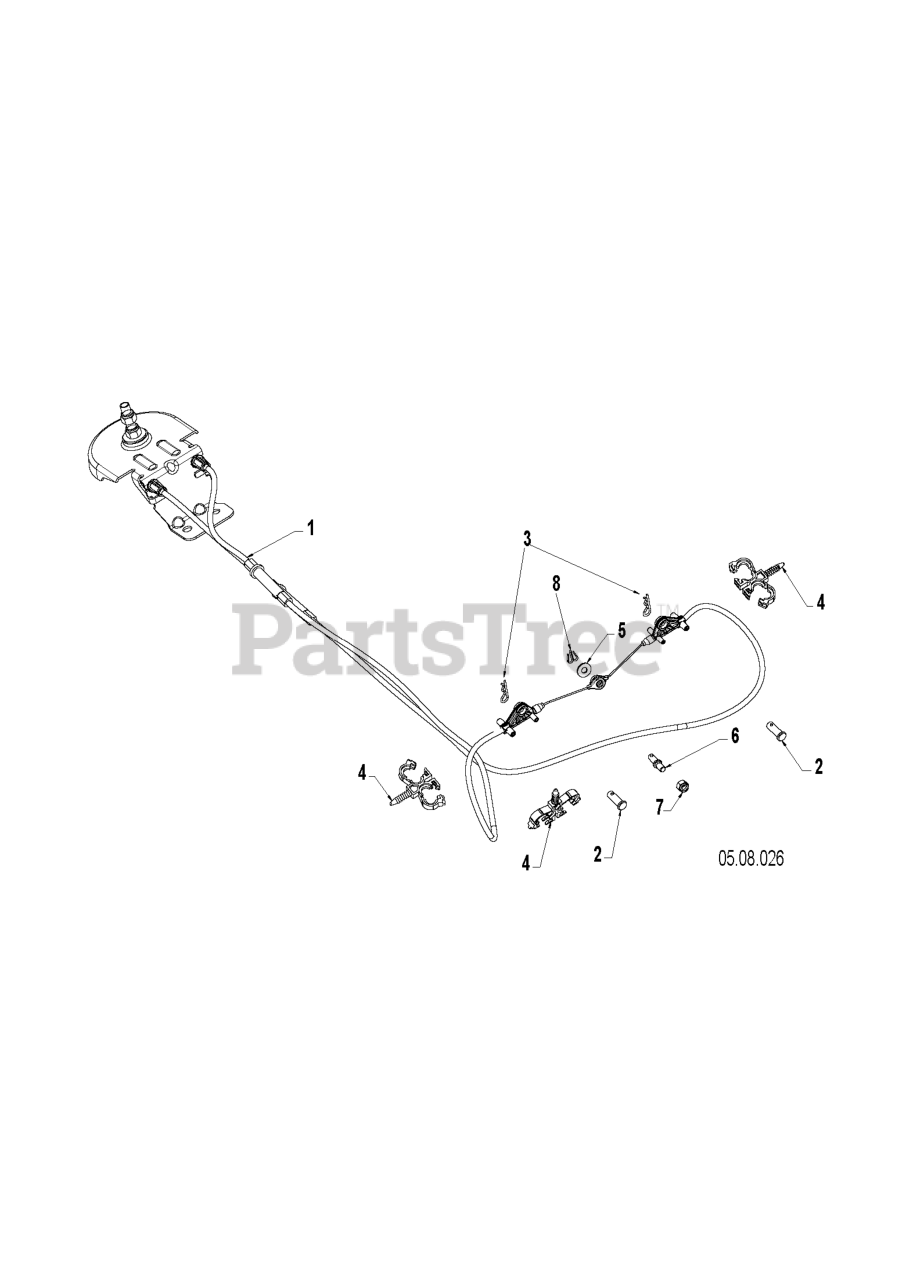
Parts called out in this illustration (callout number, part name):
2	PIN CLEVIS 5/16X.875
3	HAIRPIN.SOFT.ZINC.059X1.125
4	CLIP.CONDUIT.DOUBLE LOOP
5	WASHER FLAT_.250 X .625 X .06
7	NUT HEXAGON 1/4-20 ST ZPB
8	GSPW Retainers
